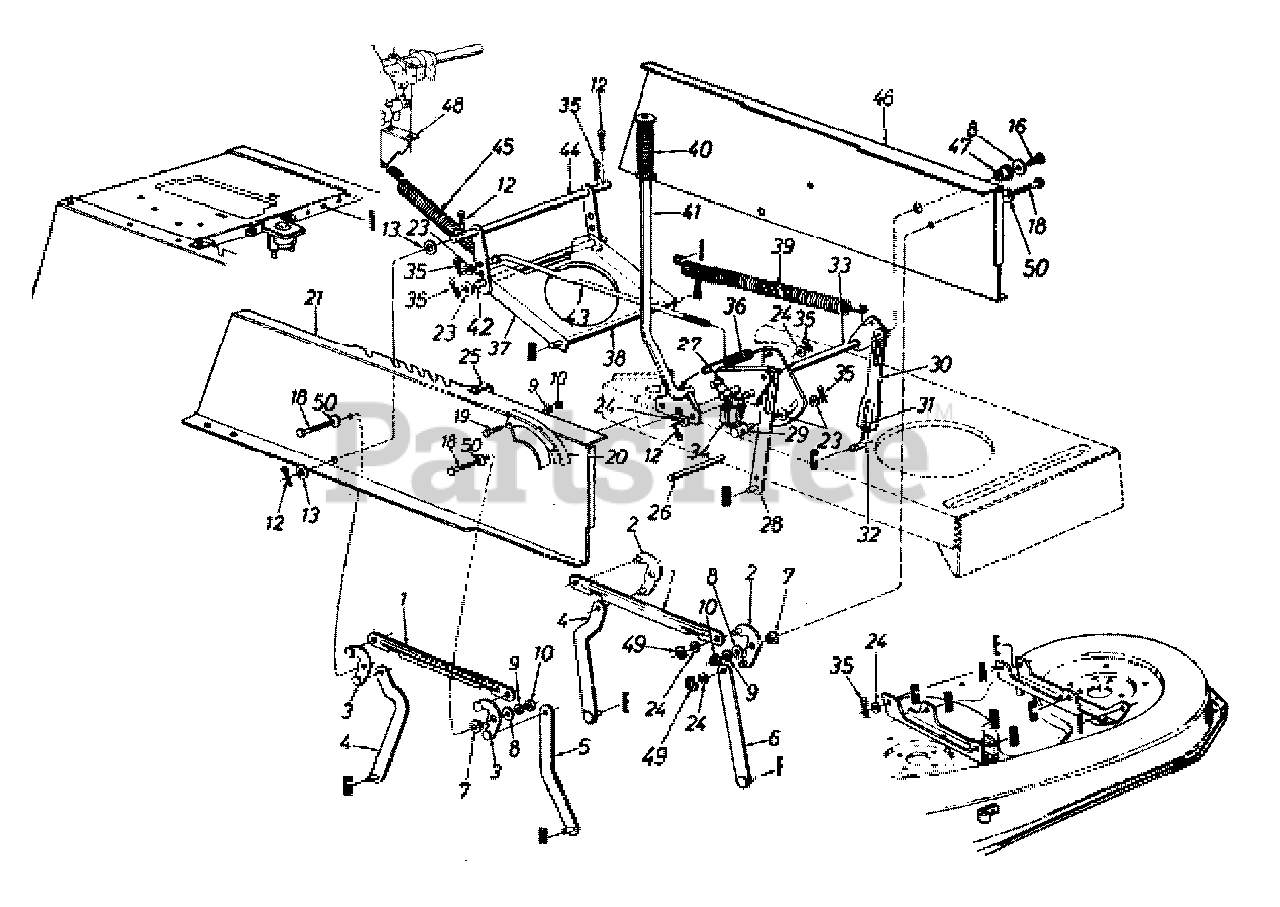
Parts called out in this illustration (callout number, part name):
3	Pivot Link Ass'y.-R.H.
7	Shld. Spacer .318" I.D.
8	Fl-Wash. .344" I.D. x .62" O.D.
9	L-Wash. 5/16" I.D.
10	Hex Nut 5/16-18 Thd. (Gr. 5)
12	Cotter Pin 1/8" Dia.
13	Fl-Wash. .635" I.D. x 1.0" O.D.
16	Hex Wash. TT-Tap Scr.5/16-18 x .75" Lg.
18	Hex Wash. Hd. Scr. 5/16-18x .875" Lg.
19	Hex Bolt 5/16-18 x .75" Lg.
24	Fl-Wash. .531" I.D. x .93" O.D.
26	Running Board Rod
27	Hex Wash. Hd. Tap Scr.
31	Hex Nut 1/2-20 Thd. (Gr. 5)
32	Lift Link Adjuster
33	Lift Shaft Ass'y.
34	Safety Switch (Deck)
35	Inter. Cotter Pin 3/8" Dia.
36	Extension Spring
39	Extension Spring
40	Grip (Lift Handle)
43	Disengagement Rod
49	"E"-Ring
50	Bell-Wash. .325" I.D.
